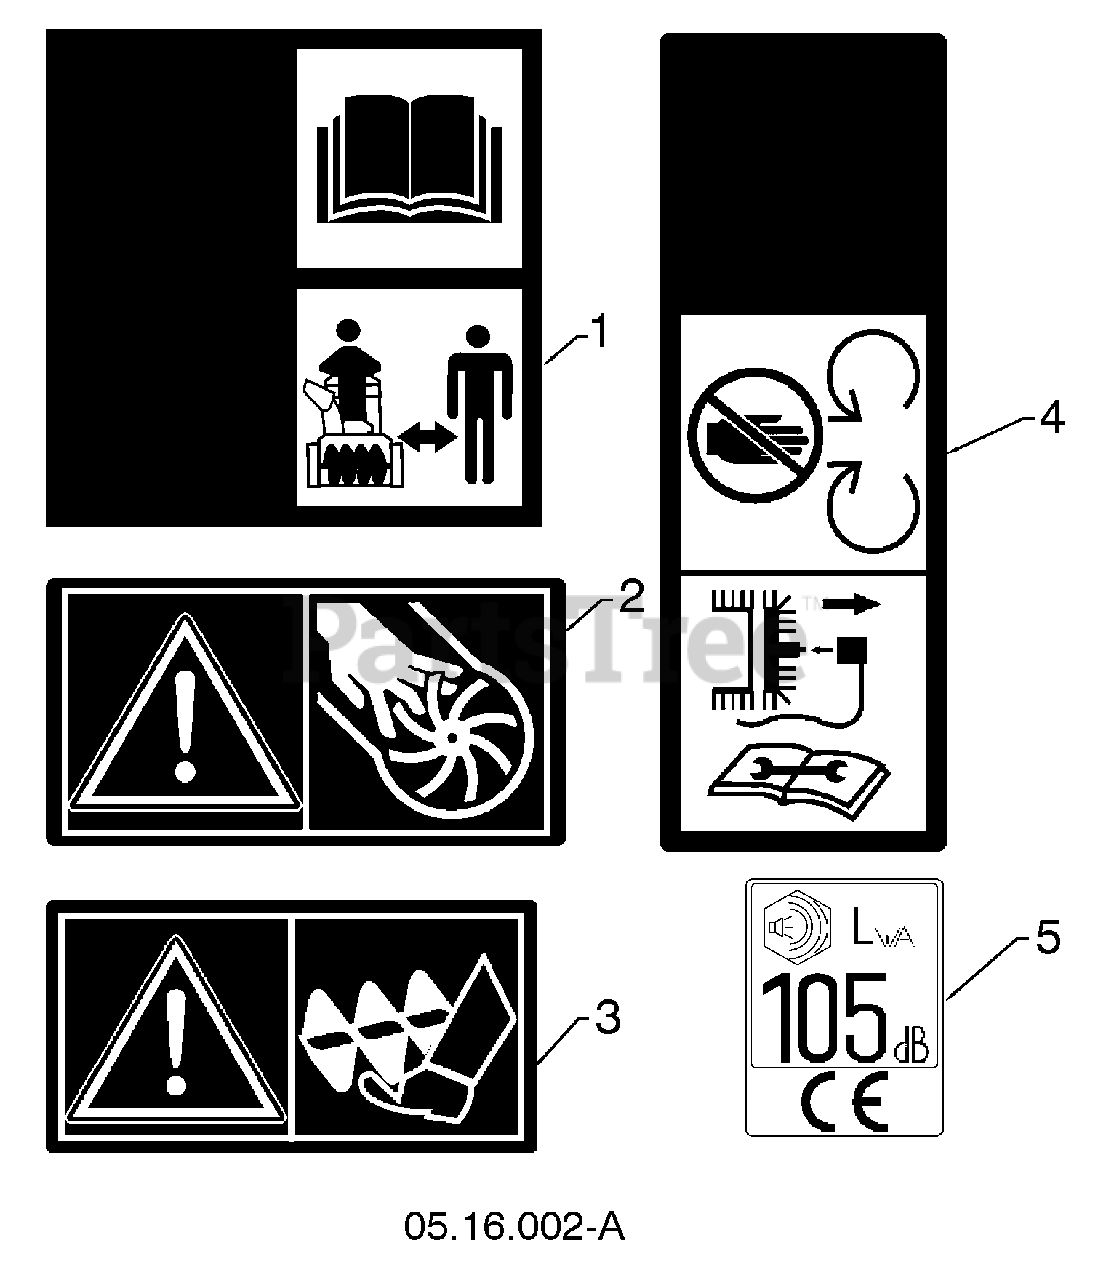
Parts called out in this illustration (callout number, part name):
1	DECAL.AUGER."
2	DECAL.CHUTE.SAFETY.
3	DECAL.AUGER.SAFETY.
4	DECAL.BELT.GUARD.
5	DECAL.FENDER
